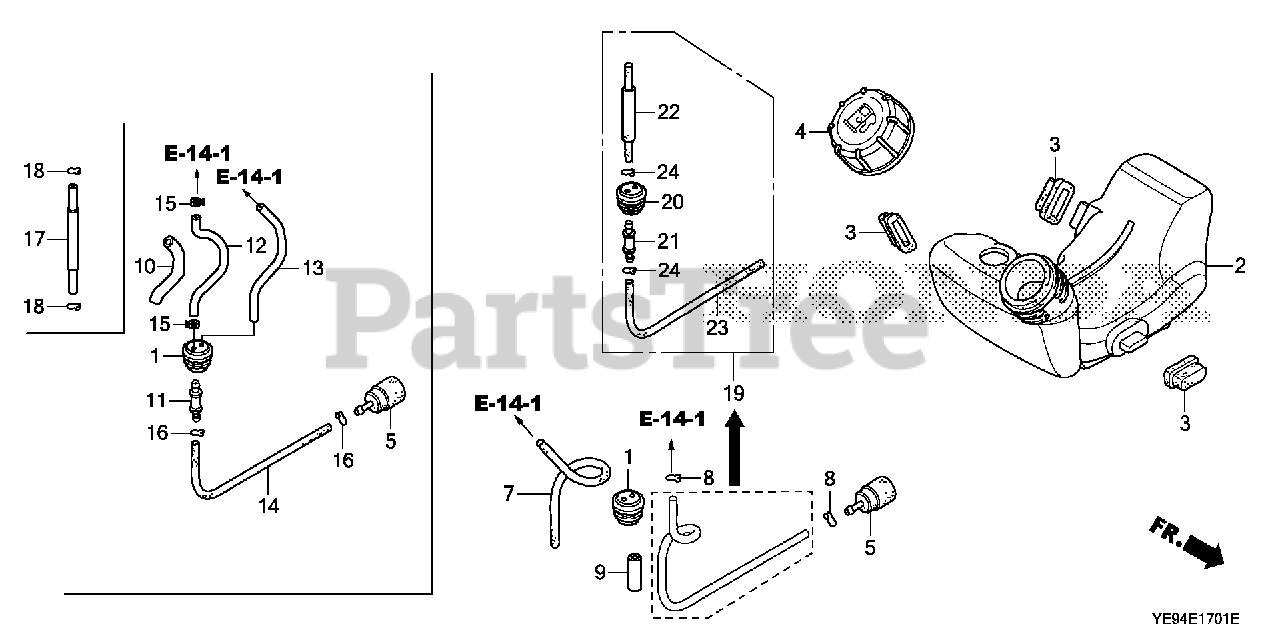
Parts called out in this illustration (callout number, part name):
1	GROMMET, FUEL TUBE
2	TANK, FUEL
2	TANK, FUEL (FOR U.S.A.)
3	RUBBER, TANK MOUNTING
4	CAP ASSY., FUEL TANK
5	FILTER, FUEL
7	TUBE, FUEL RETURN
8	CLIP, TUBE
19	GROMMET ASSY., FUEL TANK
20	GROMMET, FUEL TUBE
21	FITTING
22	TUBE, FUEL FEED
23	TUBE A, FUEL
24	CLIP, TUBE
